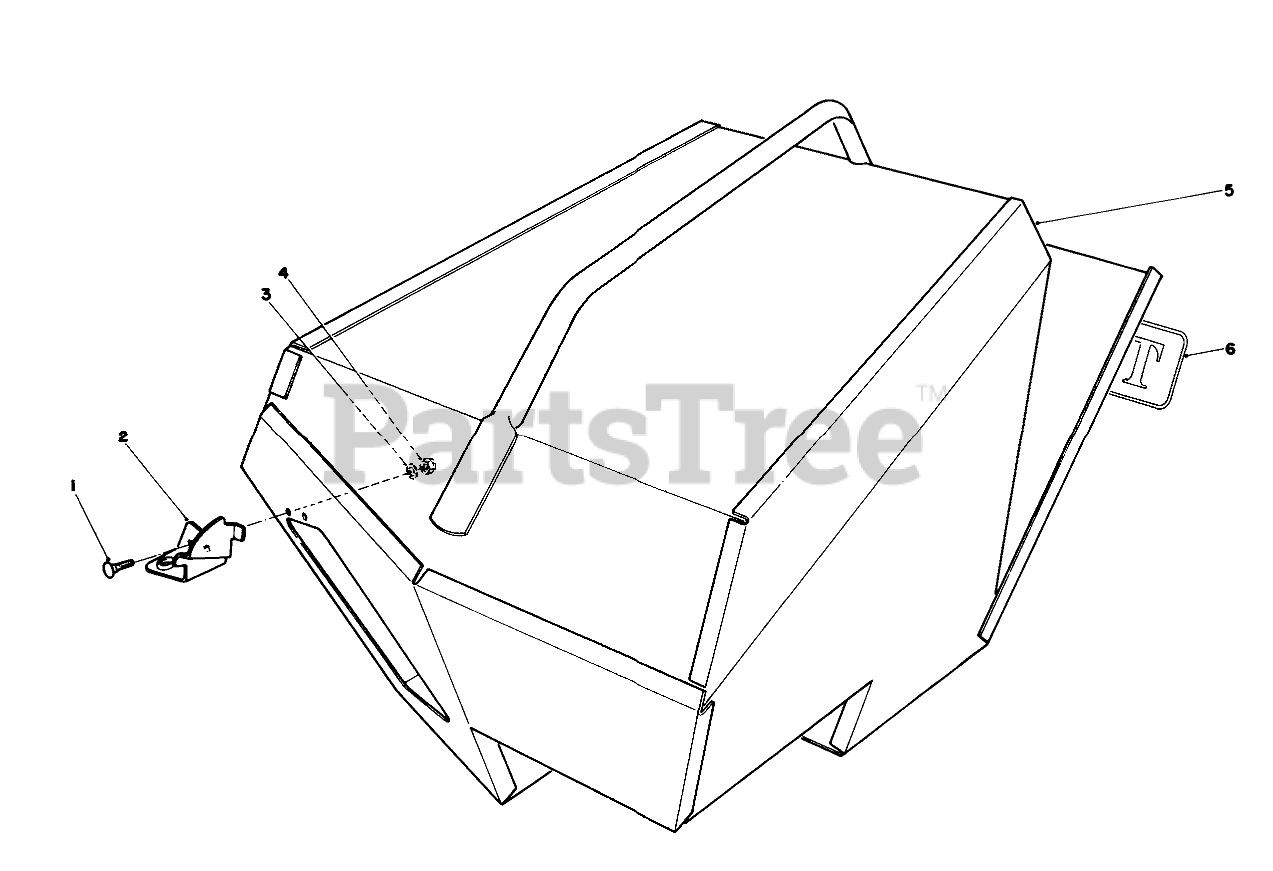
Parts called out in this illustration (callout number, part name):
1	SCREW-CARR
2	Bracket-Latch
3	WASHER-FLAT
4	NUT-LOCK, NI
5	Bag-Steel
6	Decal
